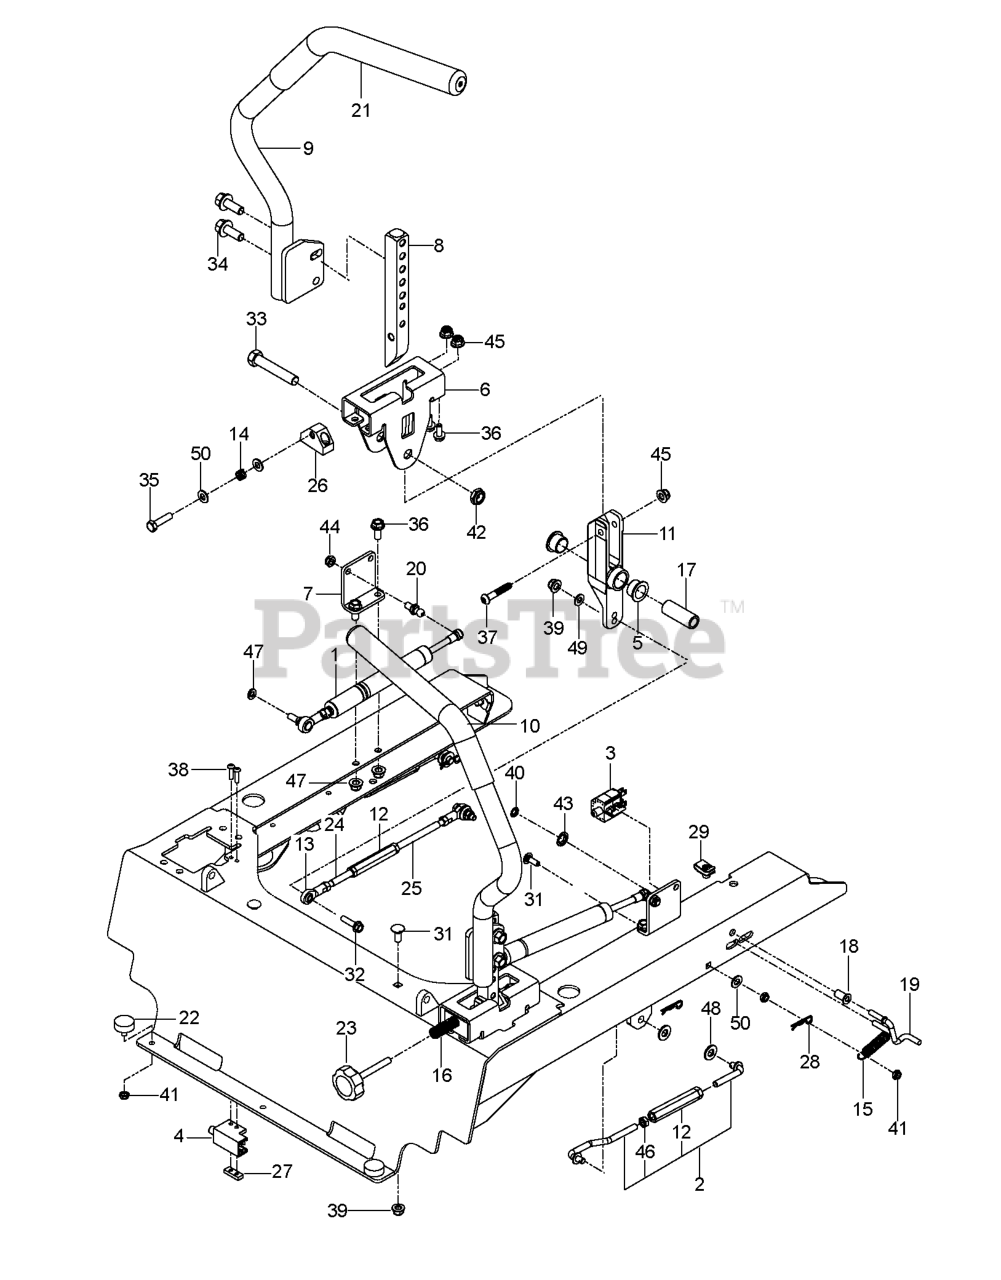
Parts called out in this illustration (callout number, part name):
1	ASSEMBLY, DAMPENER
2	ASSEMBLY, SEAT STRUT
3	SWITCH, BRAKE 3P
4	SWITCH INTERLOCKT
5	BEARING, FLANGE
6	BRACKET.CONTROL.NARROWSLOT.BLK
7	BRACKET.DAMPENER
8	LEVER, MOTION
9	LEVER.WITH GRIP.RT
10	LEVER.WITH GRIP.LT
11	LEVER.CONTROL.SHORT
12	TURNBUCKLE, 3/8
12	5/16-18 NYLOC FLANGE NUT
13	BALL JOINT, RIGHT HANDED
15	SPRING, EXTENSION
16	SPRING COMPRESSION 2.0
17	SPACER, PIVOT CONTROL
18	BUSHING, 1/4 FLANGE
19	LINK, SWITCH
20	STUD.BALL.10MM
21	GRIP - DRIVE LEVER 12"
22	BUMPER, 1/4-20 STUD, 1/4
23	KNOB
24	LINKAGE, CONTROL, FT
25	LINKAGE, CONTROL, RR
26	BLOCK TRACKING CONTROL ZTR
27	PLATE NUT ZTR
28	HAIRPIN #2
29	U-CLIP 5/16-18 NUT RETAINER
30	BOLT
31	BOLT 5/16C X 3/4" CARRIAGE
32	HHFS 5/16-18 X 1.25 TPBLT GD 5
33	HCS 1/2-13 X 2-3/4 GD 5 ZD
34	HHFS 3/8-16 X 1 GRD 5 ZD
35	BOLT.5/16-18X1-1/4 FULL.THREAD
36	HHFS 5/16-18 X 3/4
37	SCREW 5/16-18 X 1 3/4 BTN-HD
38	SCR #10-24 X .75 SKT HD BLK
39	5/16-18 NYLOC FLANGE NUT
41	JAM NUT 1/4C (2 2 PW01)
42	NUT 1/2-13 HEX JM NYL
43	NUT 3/8 PALNUT RTNG BLK PHOS
44	NUT 5/16 NYLOC
46	NUT 3/8-24 JAM
47	WASHER.LOCK.HVY.HLCL.SPR.5/16
48	WASHER
49	WASHER 5/16 FLAT
50	NUT M8 X 1.25 STD HEX
50	WASHER
